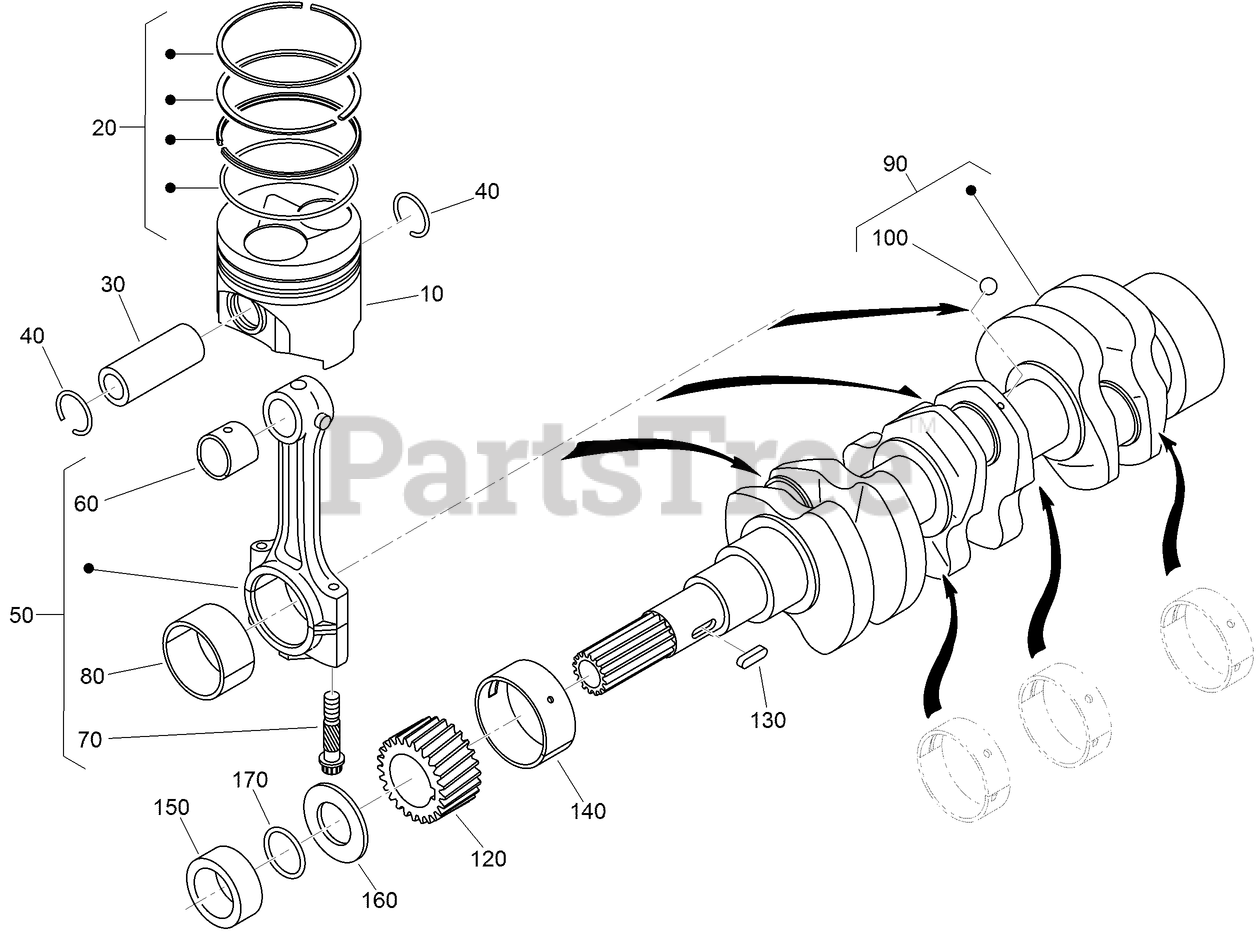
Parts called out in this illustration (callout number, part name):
10	PISTON
20	PISTON RING ASM
30	PIN-PISTON
40	CIRCLIP-INTERNAL
50	CONNECTING ROD ASM
60	BUSHING-PIN, PISTON
70	BOLT-ROD, CONNECTING
80	METAL-CRANKPIN (STD)
80	METAL-CRANKPIN (-.20MM)
80	METAL-CRANKPIN (-.40MM)
90	CRANKSHAFT
120	GEAR-CRANKSHAFT
130	KEY-FEATHER
140	METAL-CRANKSHAFT (STD)
140	METAL-CRANKSHAFT (-.20MM)
140	METAL-CRANKSHAFT (-.40MM)
150	COLLAR-CRANKSHAFT
160	SLINGER-OIL
170	O-RING
